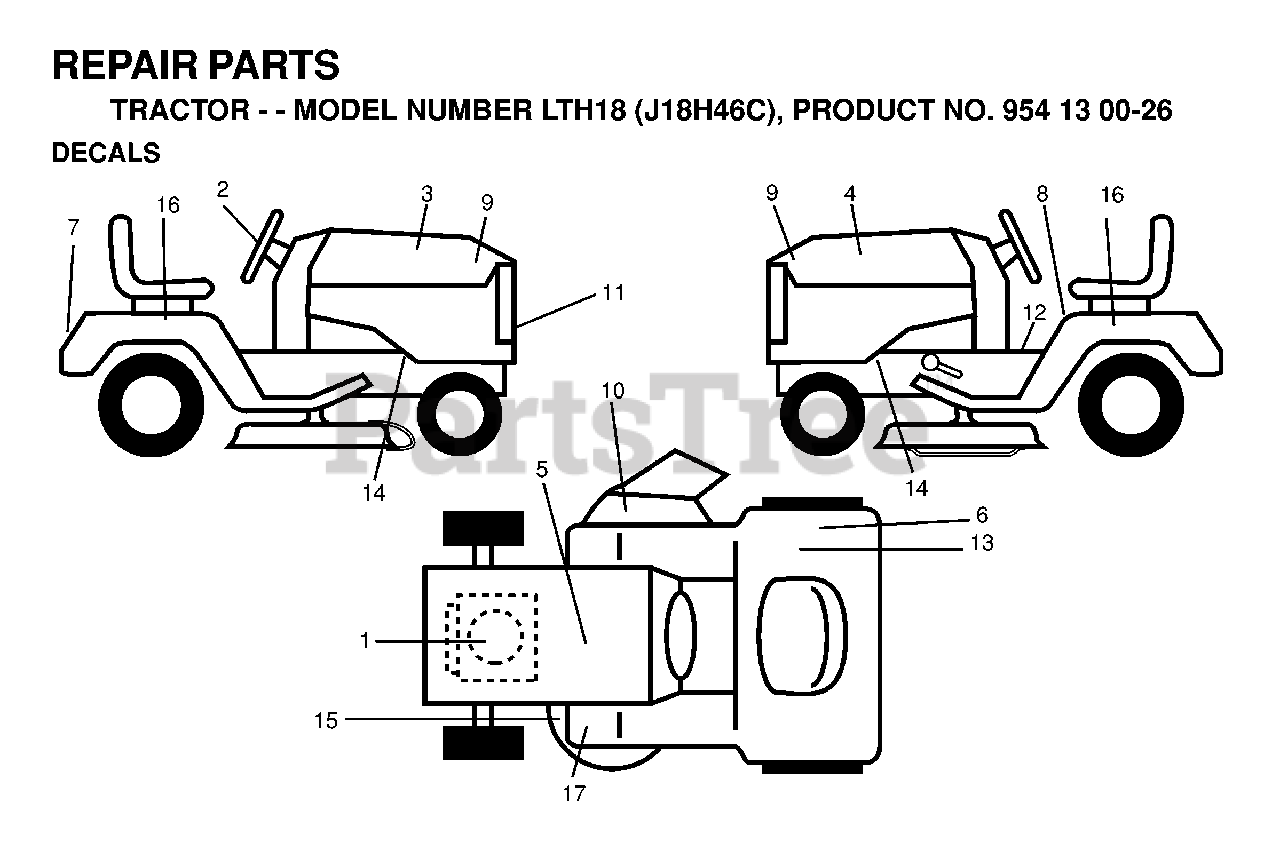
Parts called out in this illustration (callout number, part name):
5	DECAL BTRY SYMBOLS
6	DECAL CERTIFICATION
8	DECAL READ OWNER'S MAN SYMS
10	DECAL MOWER CUT/FINGER
12	DECAL PARK BRAKE
13	DECAL EUROPE STANDARD CE
15	DECAL V-BELT SCHEMATIC
